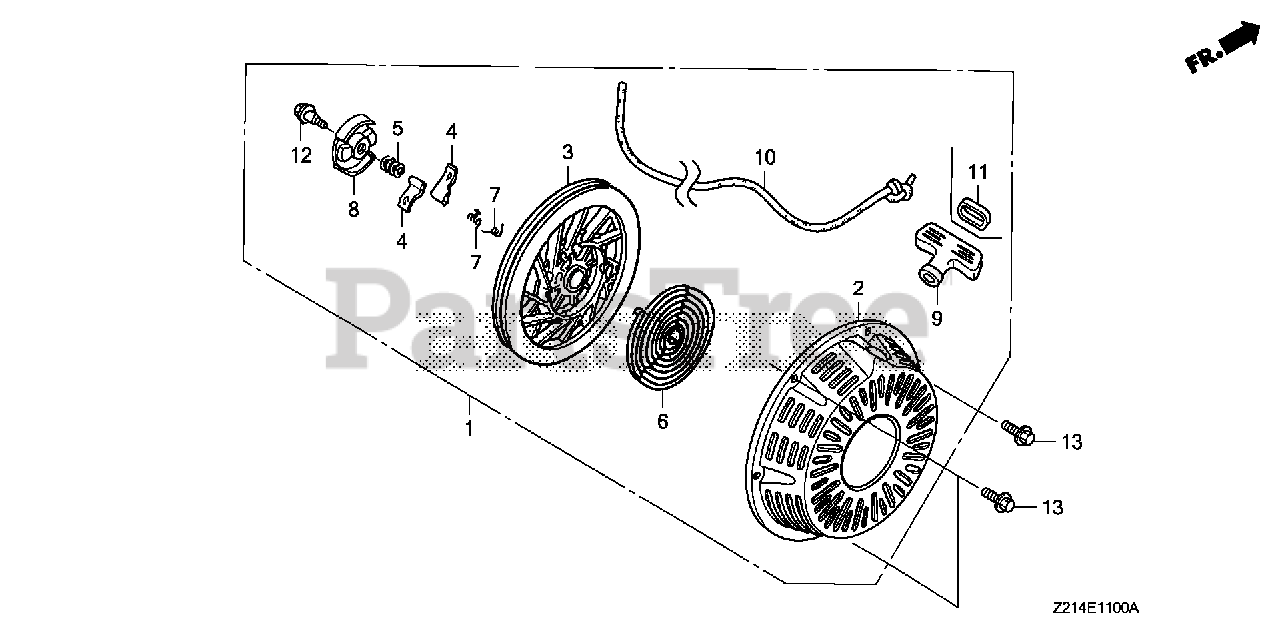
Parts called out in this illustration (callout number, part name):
1	STARTER ASSY., RECOIL *NH1* (BLACK)
2	CASE, RECOIL STARTER *NH1* (BLACK)
3	PULLEY, RECOIL STARTER
4	RATCHET, STARTER
5	SPRING, FRICTION
6	SPRING, STARTER RETURN
7	SPRING, RATCHET
8	RETAINER, SPRING
9	GRIP, STARTER
10	ROPE, RECOIL STARTER
11	GRIP, REINFORCEMENT
12	SCREW, CENTER
13	BOLT, FLANGE (6X10)
